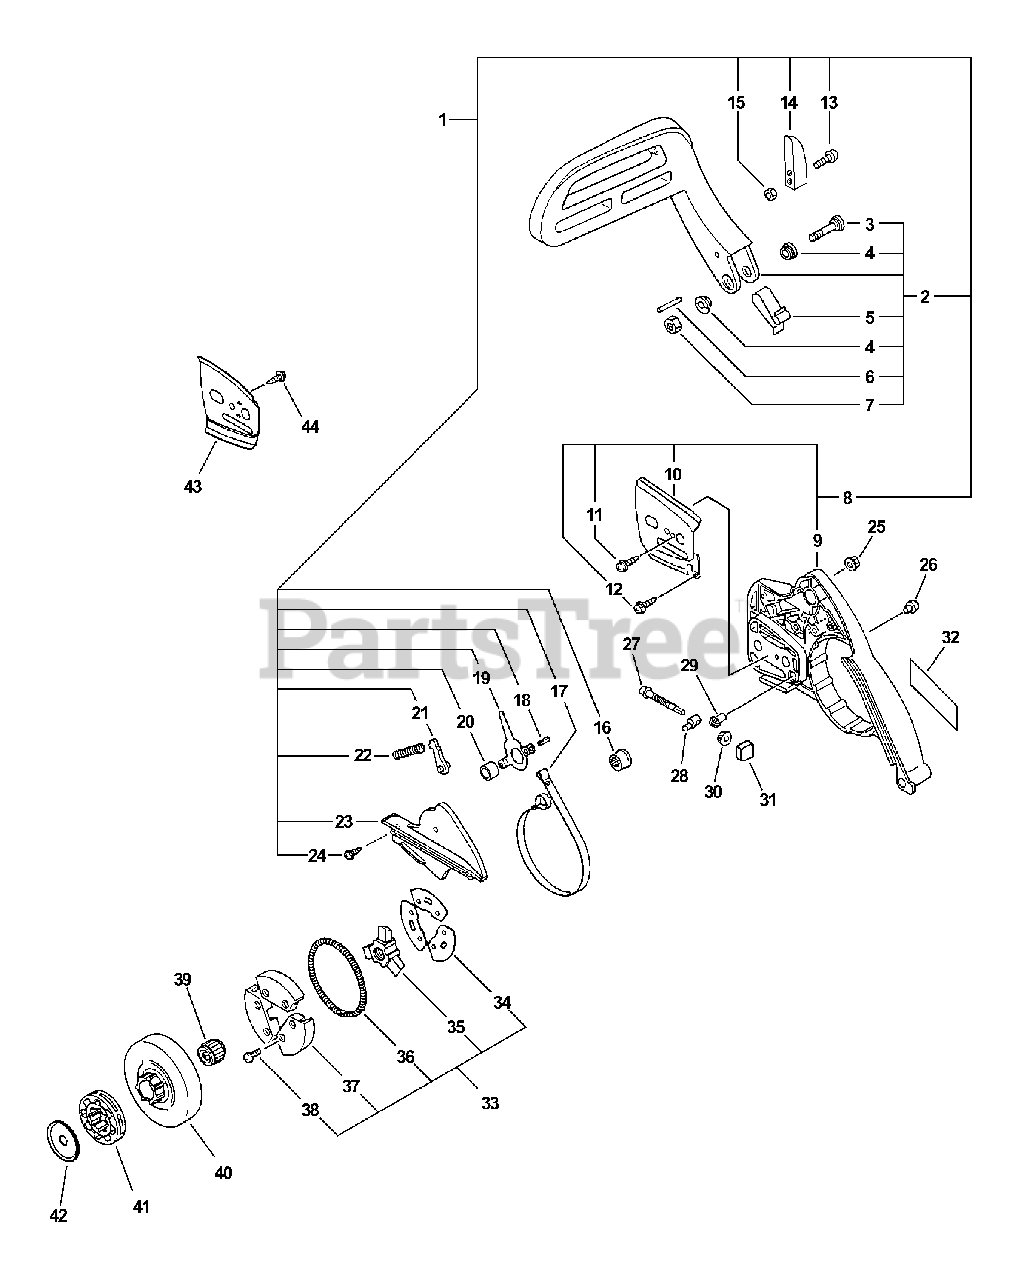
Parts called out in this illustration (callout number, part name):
1	CHAIN BRAKE ASSY
2	BRAKE LEVER ASSY
3	SCREW - 5X32
6	PIN - 3X26
7	LOCKNUT - 5
8	SPROCKET GUARD ASSY
9	GUARD, SPROCKET
10	PLATE, GUIDE - OUTER
11	SCREW - 3X6
12	SCREW - 4X10
13	SCREW - 4X18
14	WEIGHT, BRAKE
16	ADJUSTER, BRAKE BAND
17	BAND, BRAKE
18	PIN - SPRING -- 4X8
19	LEVER, BRAKE
20	WASHER - 5
21	STOPPER, BRAKE
22	SPRING, BRAKE
23	COVER, BRAKE
24	SCREW - 4X10
25	NUT - FLANGE
27	SCREW, TENSIONER
28	TENSIONER, CHAIN
29	GEAR - PINION
30	GEAR - BEVEL
31	COLLAR - 8
32	LABEL - ECHO
33	CLUTCH ASSY
34	PLATE, CLUTCH
35	HUB, CLUTCH
36	SPRING, CLUTCH
37	CLUTCH SHOE SET
38	SCREW - 4X6
39	BEARING, NEEDLE
40	DRUM, CLUTCH
41	SPROCKET, RIM
42	PLATE, CLUTCH
43	PLATE, GUIDE - INNER
44	SCREW - 4X6
